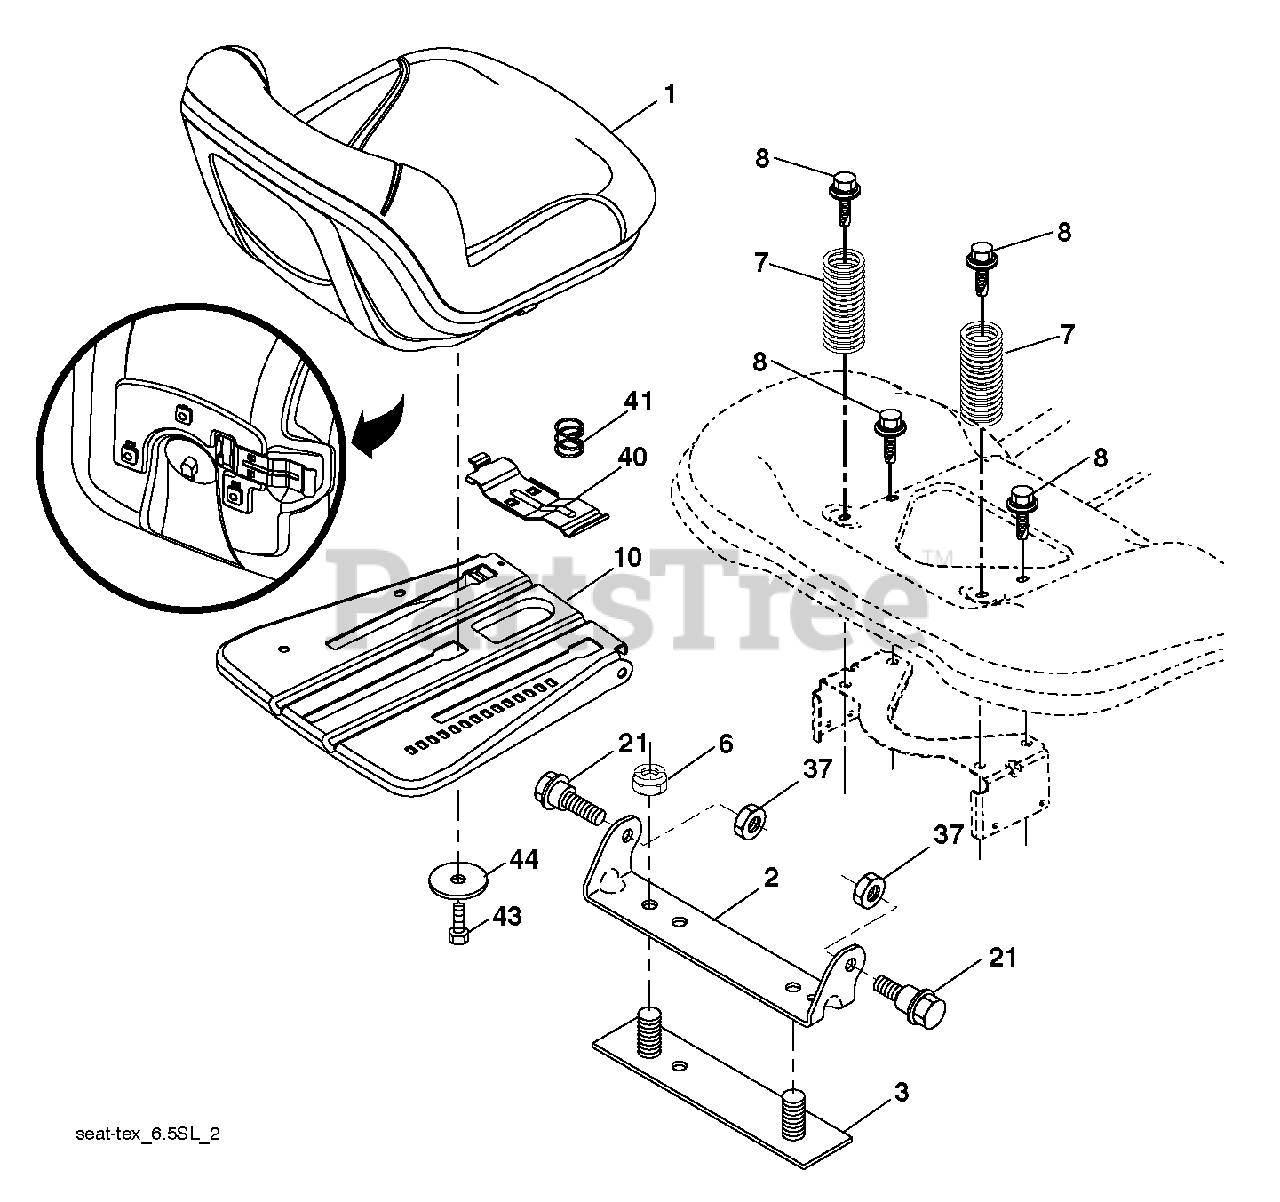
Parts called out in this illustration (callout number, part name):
1	SEAT.TH150.MS498.GRY.HUSQ.TEX
2	BRKT.PIVOT.FENDER
3	STRAP
6	NUT
7	SPRING COMPRESSION
8	BOLT, 5/16-18 X 1 3/4
10	PAN.ASM.SEAT.3PT
21	BOLT.SHOULDER.5/16-18
37	NUT.71038.31-18.HEX.NYLOCK
40	HANDLE.SLIDE.SEAT.TEX.GREY
41	SPRING.LATCH.SEAT.TEX
44	WASHER 13/32 X 2-3/8 X 12GA
